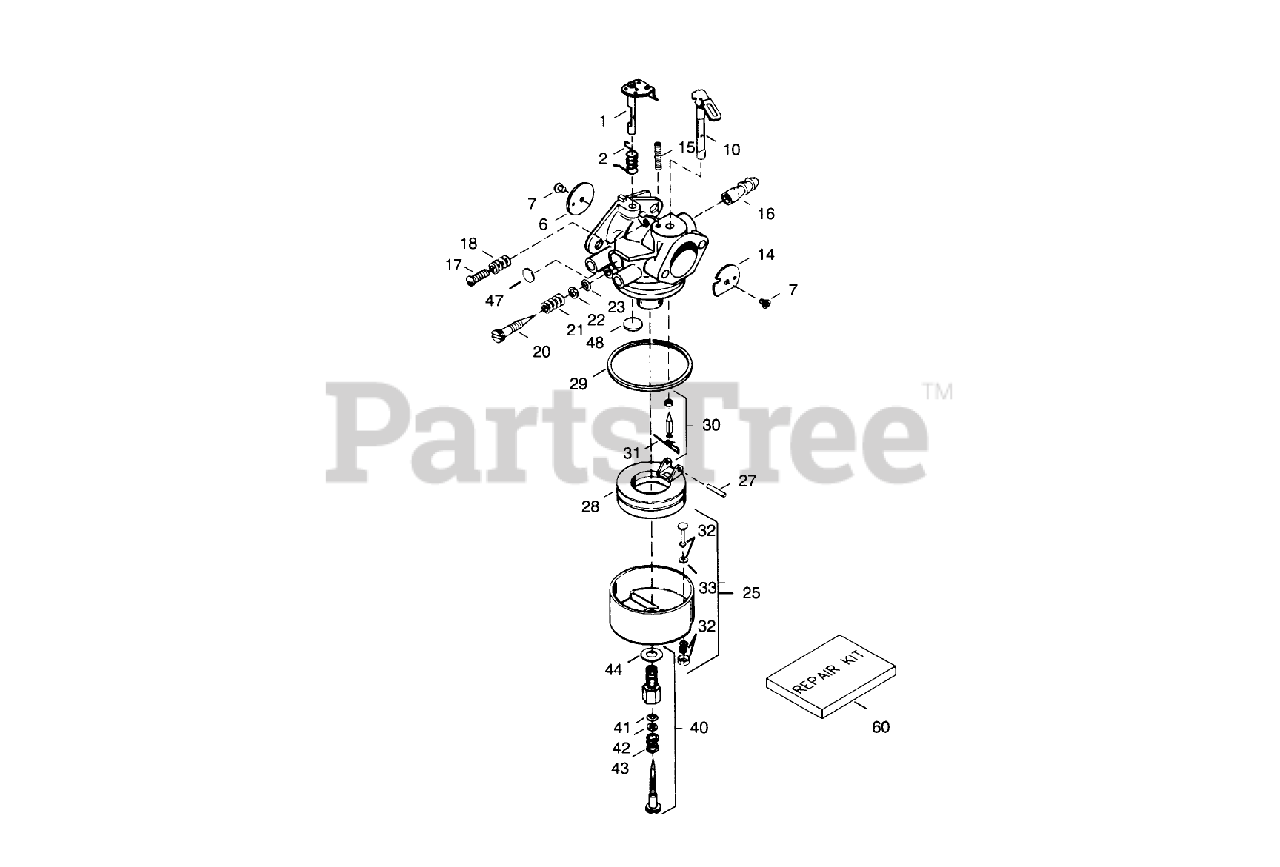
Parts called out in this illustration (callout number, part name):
1	Throttle Shaft and Lever ASM
2	Spring-Return, Throttle
6	Shutter-Throttle
7	Screw-Shutter
10	Choke Shaft and Lever ASM
14	Shutter-Choke
15	Spring-Positioning, Choke
16	Fitting-Fuel
17	Screw-Throttle Crack Screw / Idle Speed
21	Spring-Tension
22	Washer
23	ORing
24	Screw-Idle Mix
25	Float Bowl Asm. (Incl. Ref. # 32, 33)
27	Shaft-Float
28	Float
29	O Ring-Bowl, Float
30	Inlet Needle, Seat Clip Assy. (Incl. No. 13)
31	Clip-Spring
32	Bowl Drain ASM
33	Gasket-Plunger, Drain
40	Adjustment Screw Assy.,Main (Incl. Ref. #5A,21,23 30)
41	ORing
42	Washer
43	Spring
44	Washer-Bowl Nut
47	Plug-Welch, Idle Mixture Well
48	Plug-Welch, Atmospheric Vent
60	Kit-Repair
